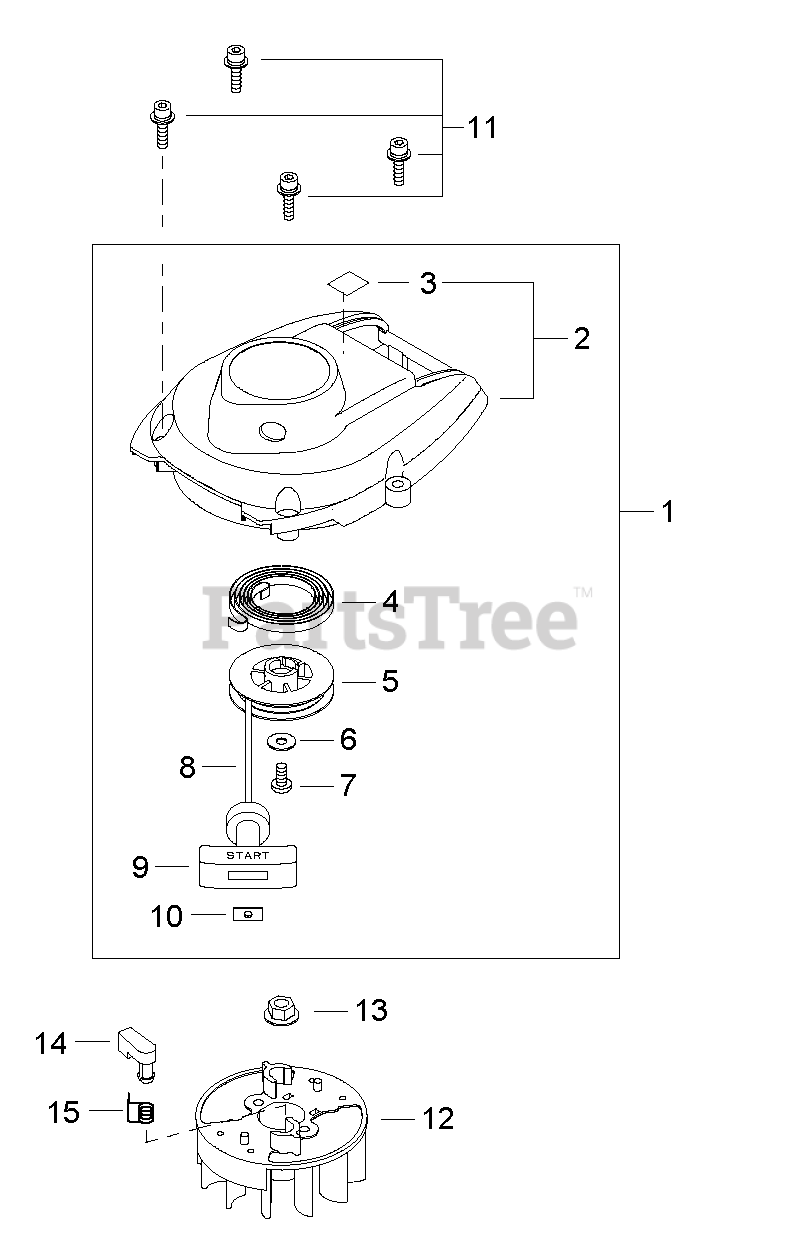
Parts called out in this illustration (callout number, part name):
1	STARTER ASSY
2	STARTER ASSY
3	LABEL - HOT SURFACE
4	SPRING, REWIND
5	REEL, ROPE
6	WASHER - 5
7	SCREW - 5
8	ROPE, STARTER
9	GRIP, STARTER
10	RETAINER, ROPE
11	SCREW - 5X20
12	FLYWHEEL
13	NUT - 8
14	PAWL, STARTER
